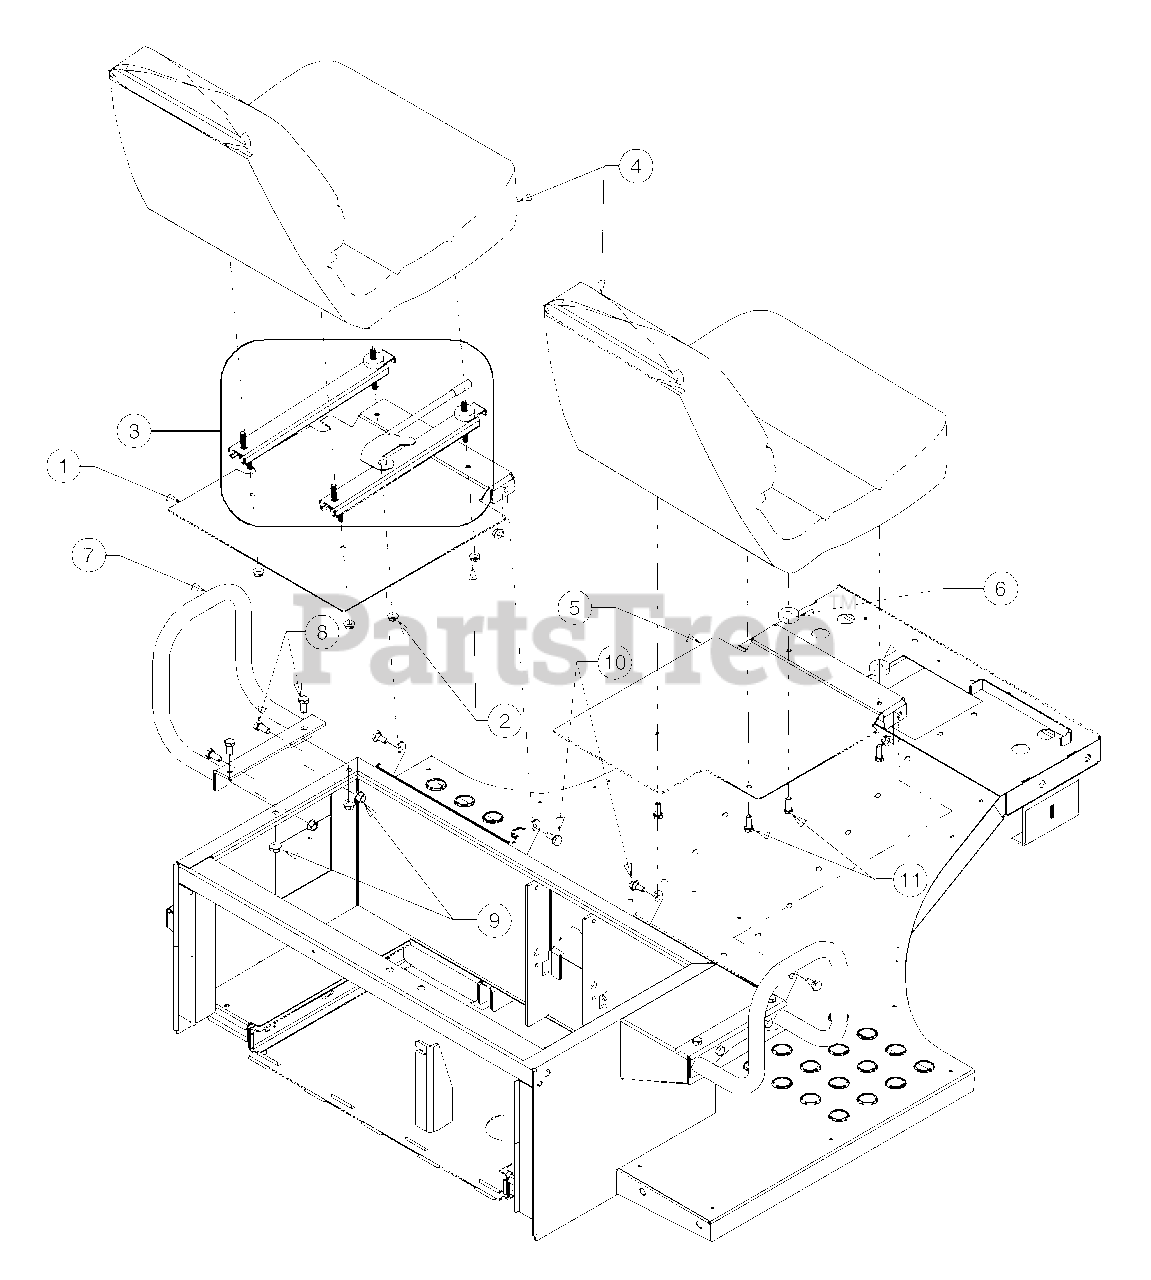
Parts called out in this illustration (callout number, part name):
1	Plate, Seat, LH
2	Nut, Flange Lock, 5/16-18, Gr5
3	Track Assembly, Seat
4	Seat
5	Plate, Seat, RH
6	Spacer, Seat
9	Nut, Flange Lock, 3/8-16
10	Shoulder Screw, .435 x .178-5/16 x .56
11	Hex Screw, 5/16-18 x .875, Gr5
